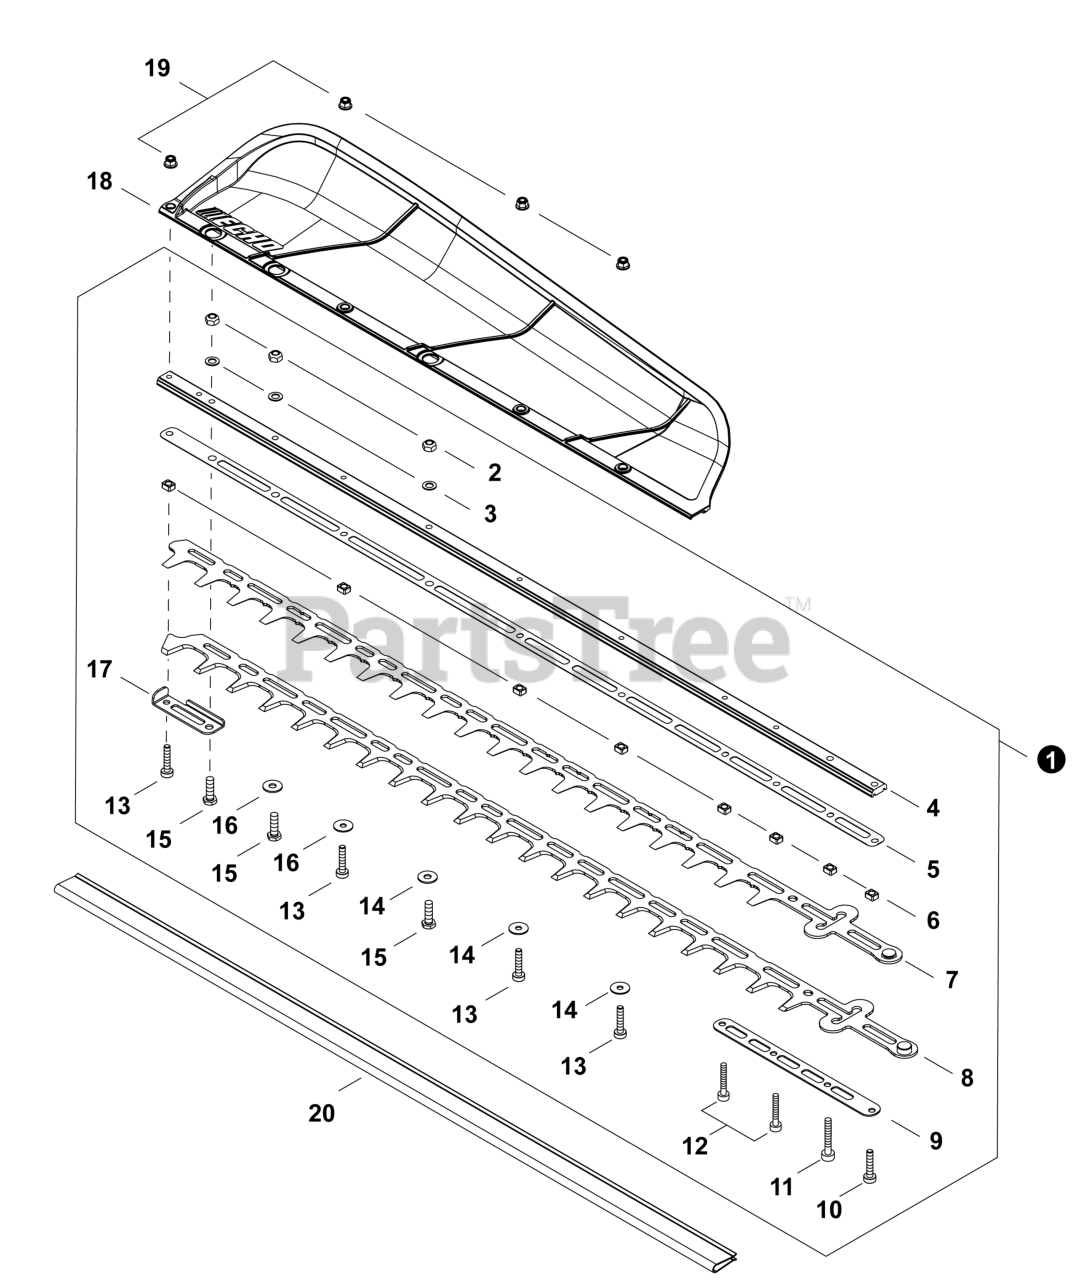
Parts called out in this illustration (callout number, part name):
1	CUTTER ASSY, 30"
3	WASHER 6.5x11.5x0.8
4	SUPPORT, CUTTER 30"
5	PLATE, CUTTER 30"
6	GUIDE, BLADE
7	CUTTER 30" - UPPER
8	CUTTER 30" - LOWER
9	PLATE, CUTTER
10	BOLT, TORX 5x25
11	BOLT, TORX 5x35
12	BOLT, TORX 5x30
13	BOLT, TORX 5x25
15	BOLT M6x20
16	WASHER M6
17	SUPPORT, CUTTER
18	DEFLECTOR, DEBRIS 30"
19	NUT, FLANGE M5
20	SCABBARD 30"
